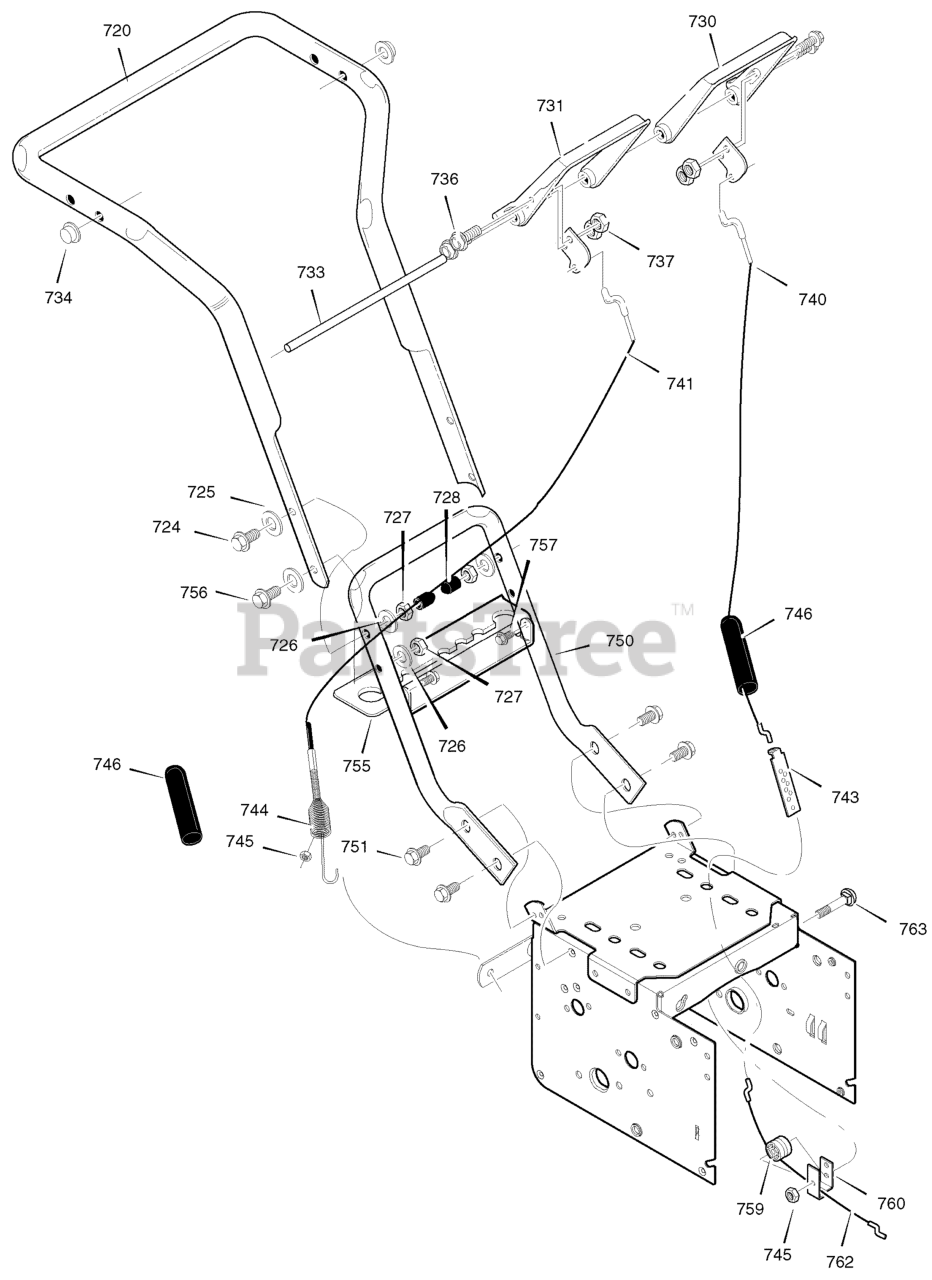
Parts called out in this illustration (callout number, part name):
725	WASHER, FLAT
726	WASHER, SPLIT
728	PLASTIC-ST OP
730	CLUTCH, LEFT HANDLE CONTROL
731	CLUTCH, RIGHT HANDLE CONTROL
733	ROD, PIVOT HANDLE
734	PUSH ON CAP
735	PLATE, CABLE PIVOT
740	CABLE, CLUTCH
741	CABLE, AUGER CLUTCH
743	BRKT, CABLE ADJUST
744	SPRING, AUGER CLUTCH
745	LOCKNUT
746	BOOT, CLUTCH SPRING
750	HANDLE, LOWER
751	SCREW 5/16-18 x 0.75
755	BRACKET, GEAR SELECTOR
756	SCREW 5/16-18 x 2
757	SCREW, 1/4-20 x 0.63
759	SPOOL-CABLE, AUGER CLUTCH
760	BRACKET, CABLE SPOOL YZ
762	CABLE, LOWER DRIVE 12"
763	BOLT, HEX 1/4-20 x 1.50 YZ
